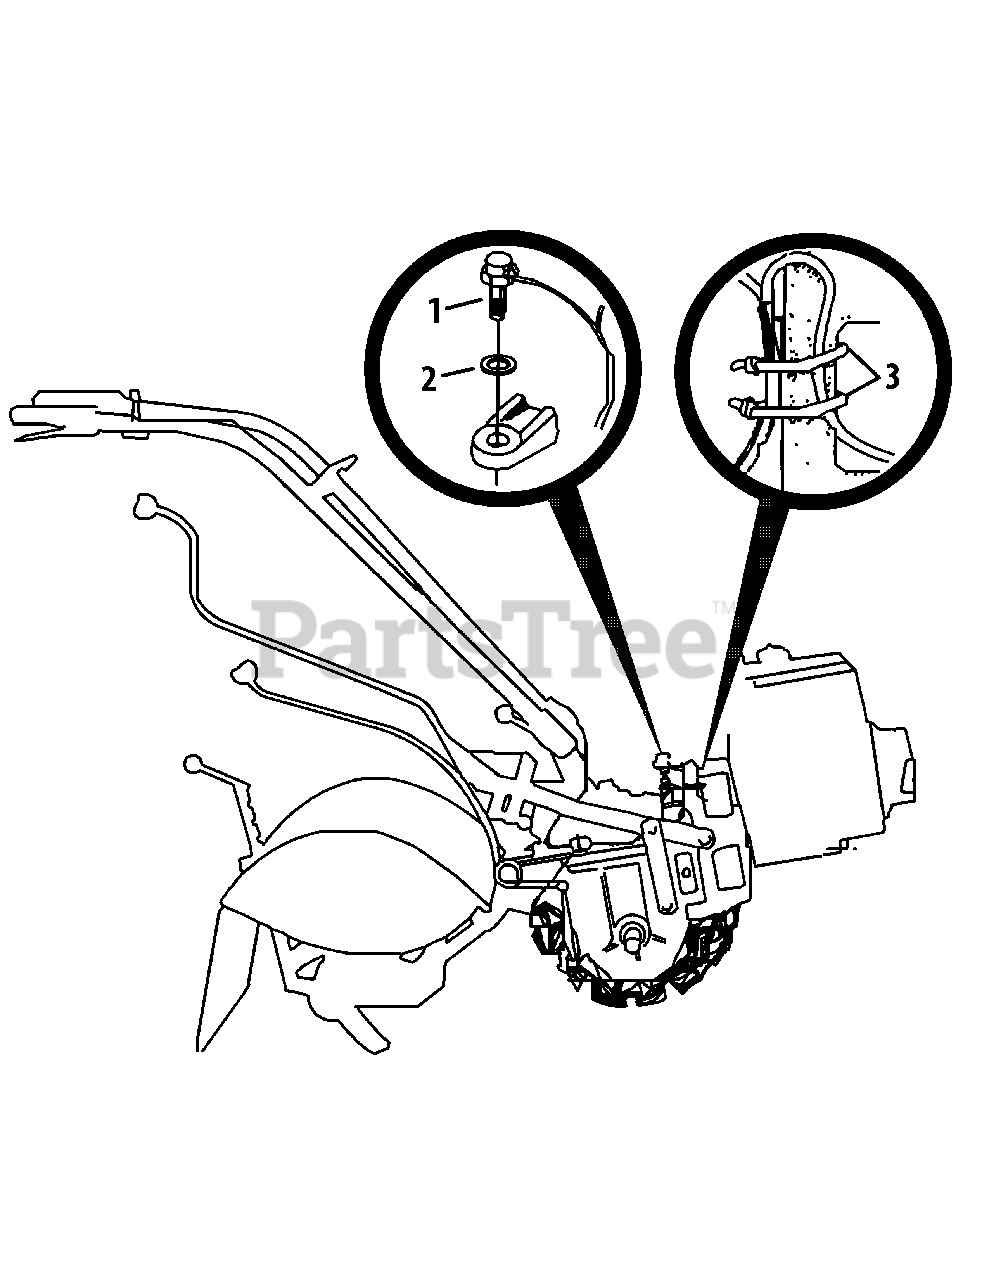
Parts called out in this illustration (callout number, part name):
1	PTO Switch
2	Internal L-Washer, 9/16"
3	Plastic Tie
